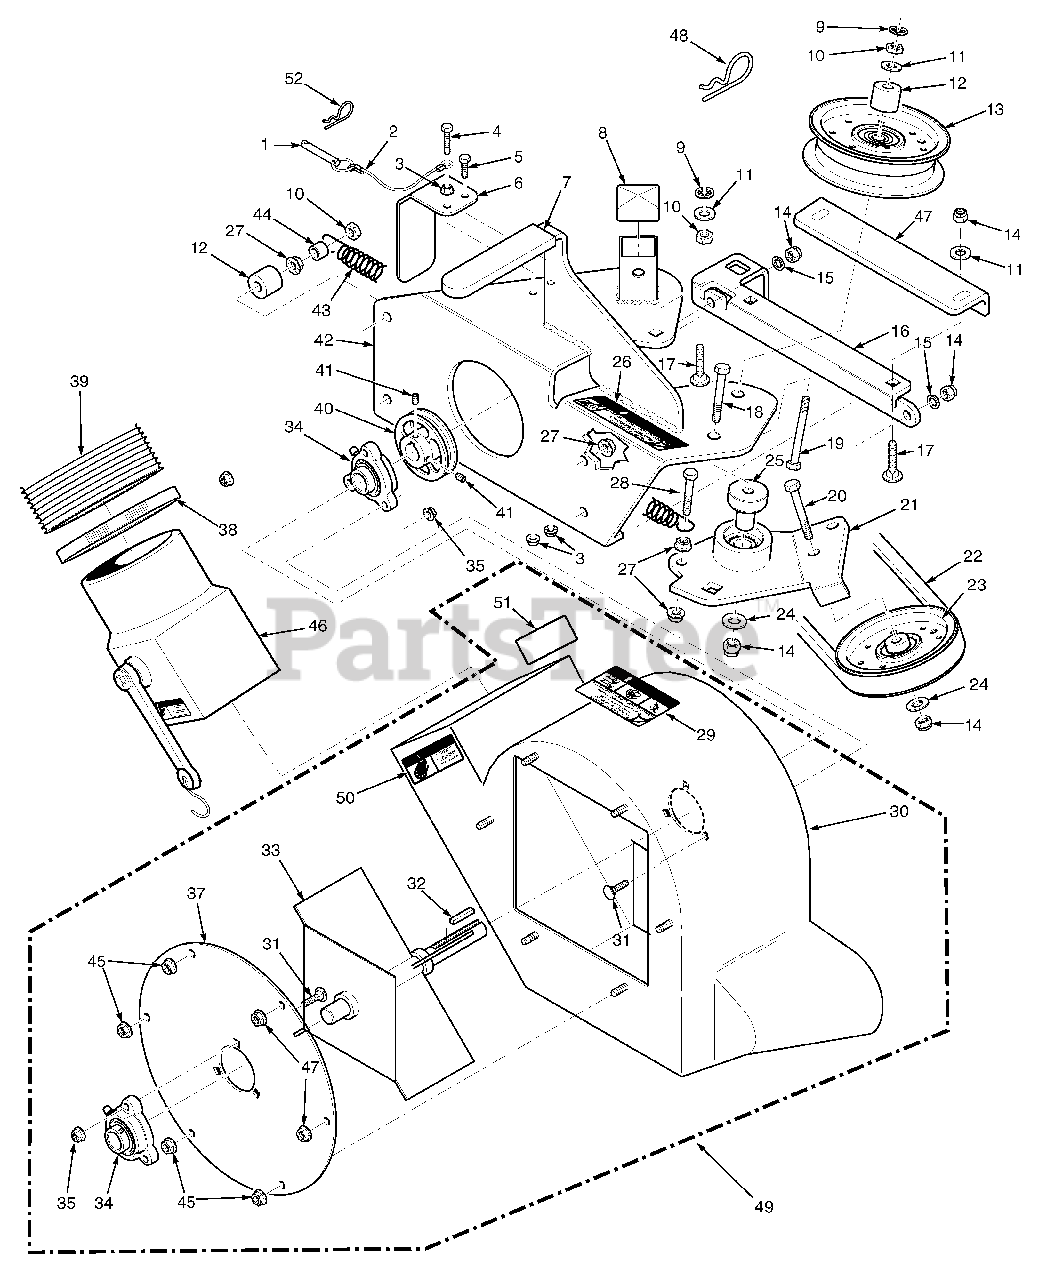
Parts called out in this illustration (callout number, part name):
1	Pin, Ring 2-1/4" Long
2	Lanyard, Deck Height Pin
3	Nut, Serr. Flange 1/4-20
4	Bolt, Hex Head 1/4-20 x 1-1/4"
5	Bolt, Hex Head 1/4-20 x 3/4"
6	Belt Cover, Rear
7	Grip, Blower Lever
8	Cap, Square
9	Nut, Push On 3/8 Thread
10	Lock Nut, 3/8-16
11	Flatwasher, 3/8-.391 x .938 x .105
12	Spacer
13	Pulley, Idler 3" Dia. - 52"
13	Pulley, Idler 4" Dia. - 61"
14	Nut, Elastic Stop 3/8-16
15	Lockwasher, 3/8-16
16	Plate, Catch Mounting
17	Bolt, Carr. 3/8-16 x 1-1/2"
18	Bolt, Hex Head 3/8-16 x 3" - 52"
18	Bolt, Hex Head 3/8-16 x 2-1/4"
19	Bolt, Hex Head 3/8-16 x 3-1/2"
20	Bolt, Hex Head 3/8-16 x 1-3/4"
21	Idler Arm Assembly, GC-STT 52"
21	Idler Arm Assembly, GC-STT 61"
22	Belt, GC-STT 52"
22	Belt, GC-STT 61"
23	Pulley, 3-1/2" O.D., GC-STT 52"
24	Washer, 3/8 Hardened
25	Pivot, Idler - 52"
25	Pivot, Idler - 61"
26	Decal, Belt Cover
27	Nut, Serr. Flange 3/8-16
28	Bolt, Hex Head 3/8-16 x 1-1/2 Gr. 8
29	Decal, Danger
30	Blower Housing w/Decals
31	Bolt, Carr. 5/16-18 x 3/4" Gr. 5
32	Key, 1/4 x 1/4 x 1-1/2"
33	Fan Weldment
34	Bearing Assembly
35	Nut, Elastic Stop 5/16-18
36	Flatwasher, 5/16-.344 x .688 x .065
37	Cover, Blower Housing
38	Clamp, 8-5/8" Max Dia.
39	Hose, 8.00" Dia. x 60.50" Long
40	Pulley, 4-3/4" O.D. - 1" Bore
41	Set Screw, 5/16-18 x 3/8"
42	Frame, Blower Mount - 52"
42	Frame, Blower Mount - 61"
43	Spring, Main Drive
44	Spacer
45	Nut, Serr. Flange 5/16-18
46	Adapter w/Strap
47	Plate, Blower Catch
48	Hair Pin Cotter, .243 x 4"
49	Blower Housing Assembly, GC-STT
50	Decal, Rotating Blower
51	Decal, Blower
52	Hair Pin Cotter, .177 x 3-1/4"
